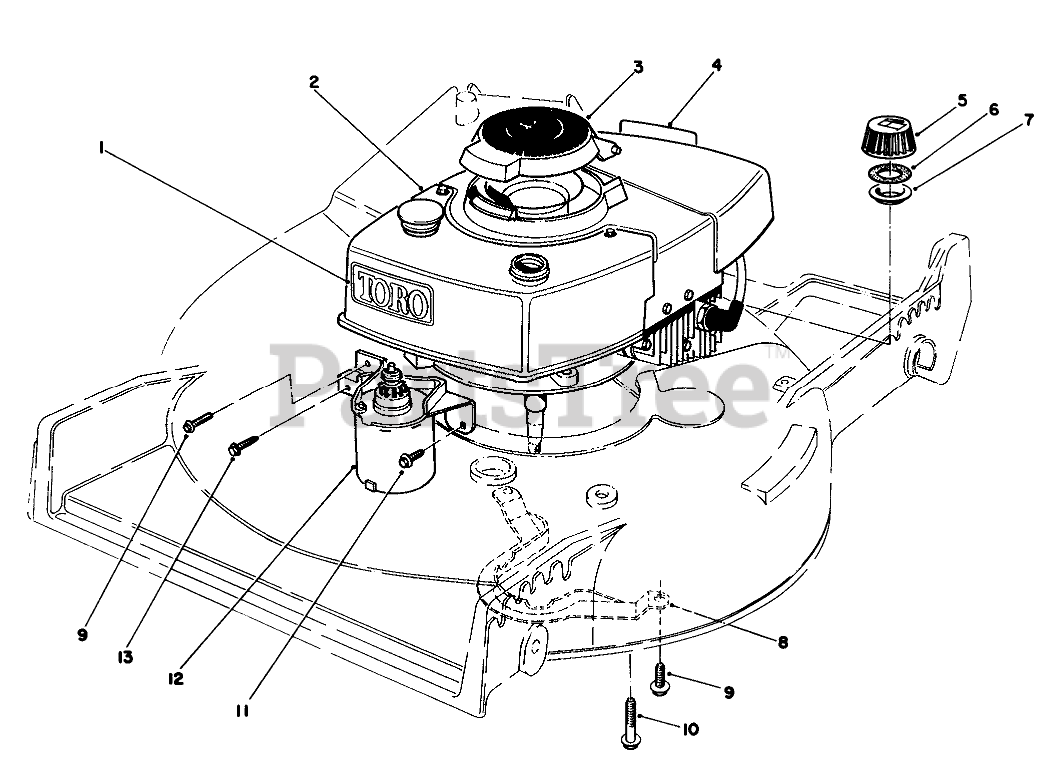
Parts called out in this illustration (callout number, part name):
1	Decal Tow
2	Engine
3	COVER ASM
4	Decal-Maintenan
5	Gas Cap (Incl. Ref. #6 & 7)
6	GASKET
7	GAS CAP BAFFLE
8	BELT GUIDE
9	Screw
10	3/8-16 X 2 CAPSCREW
11	SCREW
12	STARTER MOTOR ASM
13	SCREW AND WASHER ASM
